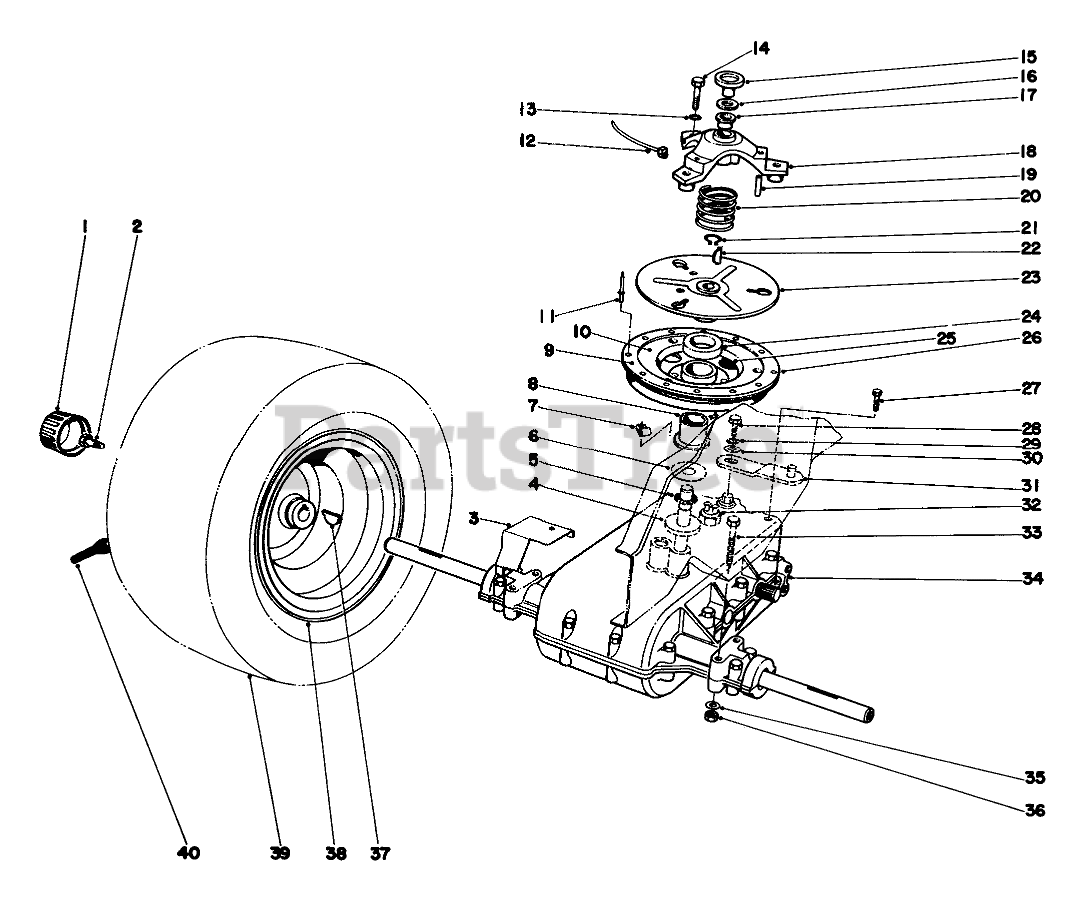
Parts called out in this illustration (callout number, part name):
1	Cap-Hub
2	Capscrew
3	GRASS SHIELD B
4	SPACER
5	NEEDLE BRG
6	THRUST WASHER
7	CLIP-FUEL LINE
8	Bushing
9	CLUTCH PAD
10	Retainer Ring
11	Rivet
12	Push Mount Tie
13	WASHER-LOCK
14	SCREW-HH
15	CLUTCH CAP
16	THRUST RACE
17	BUSHING-FLANGE
18	Clutch Cover (Incl. Ref. #17 & 19)
19	NEEDLE BRG
20	COMPRESSION SPRING
21	RING-SNAP, EXTERNAL
22	KEY-WOODRUFF
23	Clutch Plate
24	Felt Washer
26	Sheave Assembly (Incl. Ref. #8-11)
27	SCREW-HWHTF
28	SCREW-HH
29	WASHER-LOCK
30	WASHER-FLAT
31	SHIFT LEVER WA B
32	Switch-Neutral
33	SCREW-HH
34	Transaxle
35	WASHER-PLAIN
36	NUT-LOCK, CONE
38	Rim
39	16 X 7.5-8 REAR TIRE
40	STEM-VALVE
